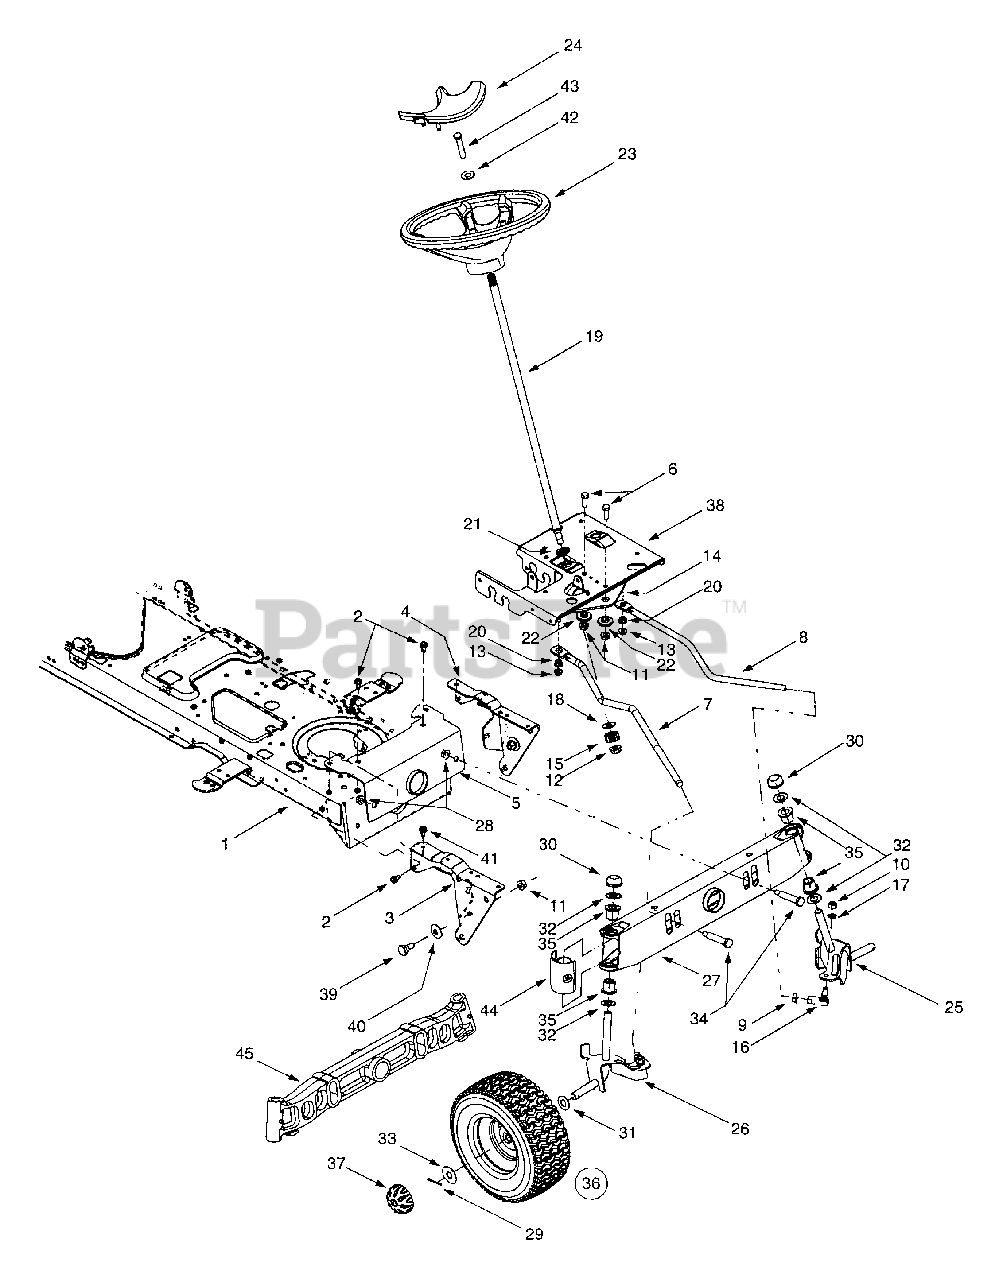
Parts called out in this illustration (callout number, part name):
6	Hex Cap Screw, 3/8-16 x 1 (Grade 5)
7	RH Drag Link
8	LH Drag Link
9	Jam Nut, 7/16-20 (Grade 2)
10	Hex Nut, 3/8-24 (Grade 2)
11	Flange Lock Nut, 3/8-16
12	Flange Lock Nut, 7/16-20
13	Flange Lock Nut, 5/16-18
14	Steering Gear, 11/90 Ratio
15	Steering Pinion Gear
16	Ball Joint, 7/16-20
17	Lock Washer, 3/8
18	Flat Washer, .51 x 1.12 x .06
19	Steering Shaft, .625 OD x 24.4
20	Plastic Bushing, .38 ID
21	Hex Flange Bearing, 5/8
22	Shoulder Spacer, .38 ID
23	Steering Wheel
24	Steering Wheel Cap, w/ Icon
25	LH Axle Assembly, .625 Diameter
26	RH Axle Assembly, .625 Diameter
28	Flange Lock Nut, 3/8-16
29	Cotter Pin
30	Push Cap, .625
31	Flat Washer, .64 x 1.0 x .12
32	Flat Washer, .64 x 1.24 x .06
33	Flat Washer, .635 x 1.589 x .06
34	Shoulder Screw, .5 x 2.2, 3/8-16
35	Flange Bearing, .632 ID x .937 OD
37	Hub Cap
39	Shoulder Screw, 3/8-16
40	Bell Washer, .39 x 1.13 x .062
41	Self-tapping Screw, 5/16-18 x .75
42	Bell Washer, .34 x .872
43	Hex Bolt, 5/16-18 X 1
44	Pivot Bar End Cap
45	Cast Iron Pivot Bar w/ Fittings, .625
